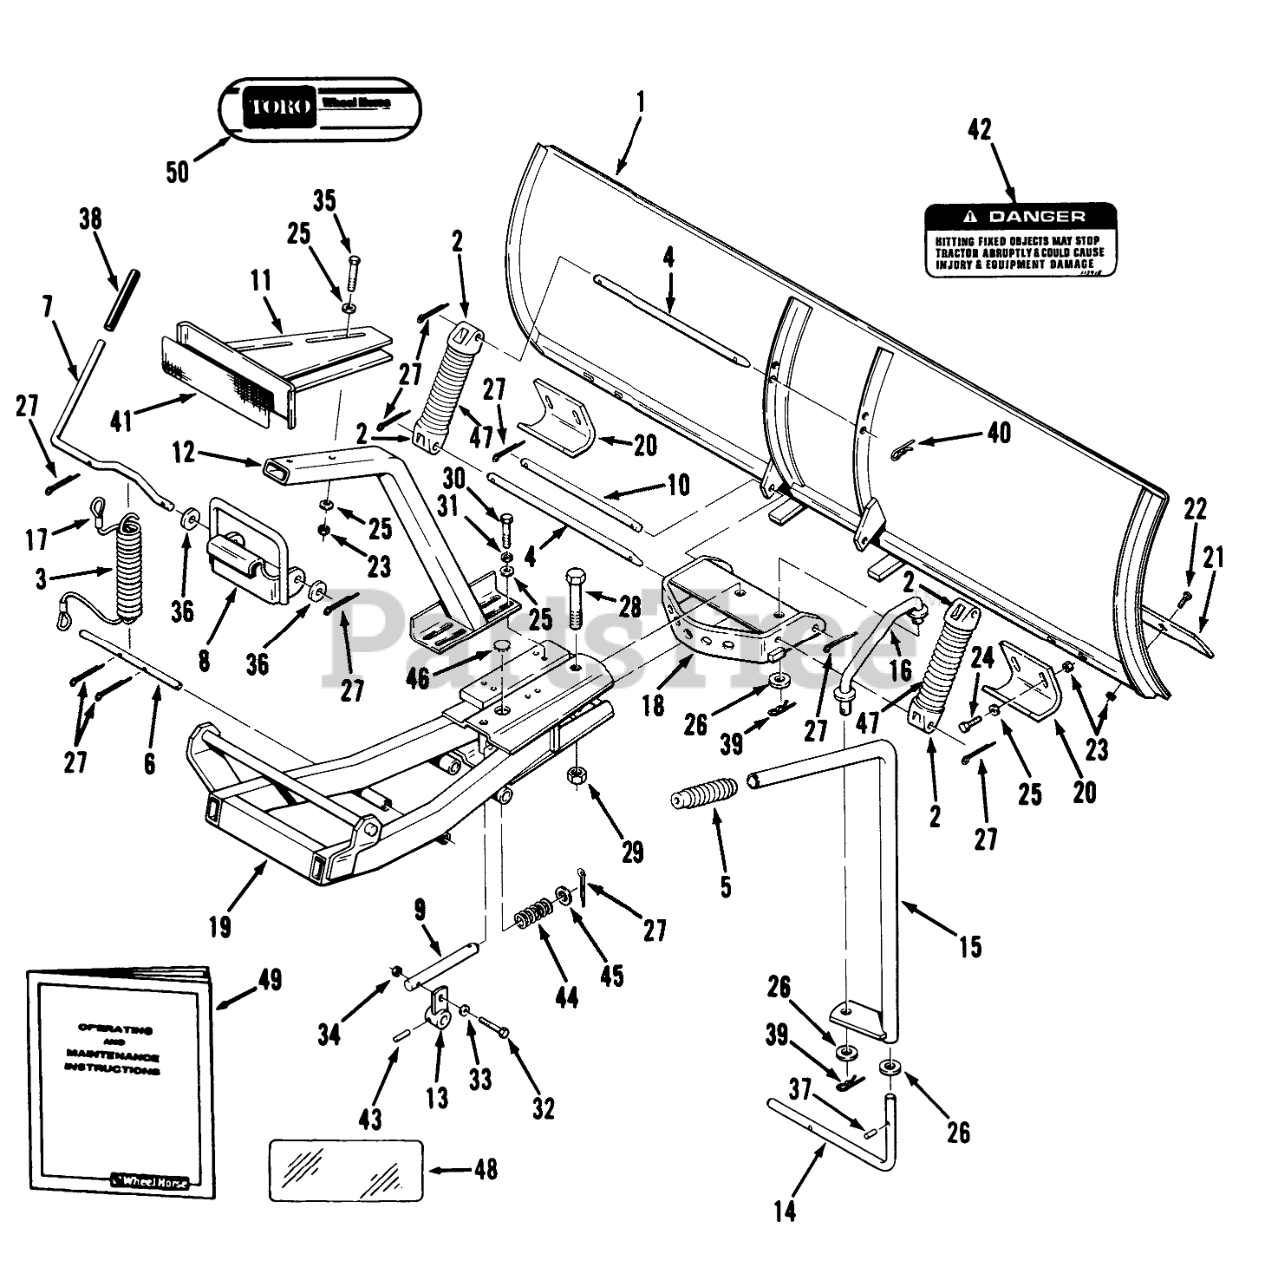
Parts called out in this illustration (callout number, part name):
1	WLDMT-BLADE 56"
2	Lug
3	SPRING
4	ROD-PIVOT, BLADE
5	HANDGRIP
6	SHAFT-LOWER R
7	SHAFT-UPPER
8	WLDMT-BRKT & HAND B
9	Pin Index
10	ROD-LOWER
11	WLDMT-PEDAL UPPER R
12	WLDMT-PEDAL LOWER R
13	WLDMT-LEVER INDEX R
14	SHAFT-INDEX R
15	HANDLE INDEX R
16	WLDMT-ROD INDEX
17	Cable
18	WLDMT-QUADRANT R
19	WLDMT-FRAME BLADE R
20	SKID
21	PLATE-BLADE EDGE
22	Bolt-Carriage
23	NUT
24	Bolt
25	Washer
26	Washer
28	Bolt
29	Nut
30	Bolt
31	LOCKWASHER
32	Bolt
33	Collar
34	Nut
35	Bolt
36	Washer
37	PIN-SPIROL
38	GRIP
39	PIN-4
40	Hairpin
41	PAD FOOTREST
42	DECAL-DANGER
43	PIN-SPIROL
44	Spring
45	WASHER
46	PLUG
47	Spring
48	DECAL-OVERLAY
49	Operator-s Manual
50	Decal
